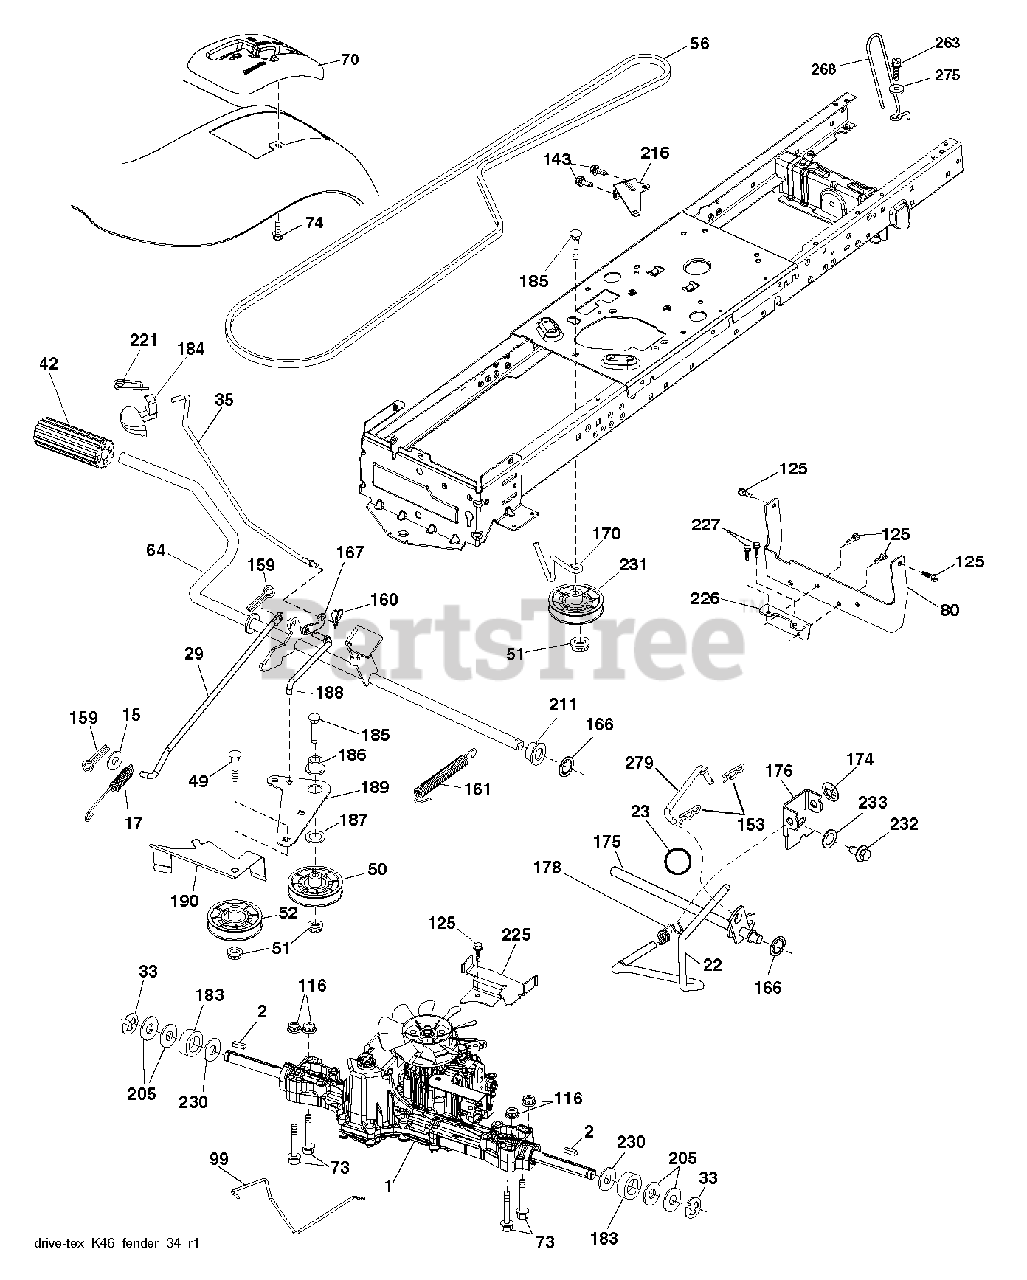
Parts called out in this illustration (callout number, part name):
2	SQUARE KEY
17	SPRING.BRAKE.K46.GREEN
22	ROD.SHIFT.FENDER.TLT.2006
23	KNOB.DUCKHEAD.1/2
29	ROD.BRAKE.K46
33	E-RING LT
35	ROD, BRAKE, PARK
42	PEDAL COVER T
49	BOLT
50	IDLER.FLAT.910.OFFSET
51	NUT LOCK FLG 3/8-16 UNC
52	IDLER.V-GROOVE.910.OFFSET
64	SHAFT.ASM.PEDAL.BRAKE.
74	SCREW.HI-LO.CONSOLE
80	STRAP.TORQUE.K46.K57R.TT
99	ROD.SPRING.BYPASS.K46.LT.Z
116	NUT LOCK HEX FLANGE 5/16-18
125	SCREW
153	RETAINER M
159	COTTER PIN
160	RETAINER CLIP
161	SPRING, RETURN LT
166	NUT.PUSH.625
167	LATCH.BRAKE.SPRING
170	KEEPER.CENTER SPAN.1.688
174	NUT.PUSH.500.2006
175	SHAFT.ASM.SHFT.T2.TLT
176	ARM.CLEVIS.ROD.SHIFT
178	SPRING.SHIFT.GT2006
183	SPACER AXLE
184	HANDLE.PARKING.BRK.PRED.LT.RED
186	SPACER.RETAINER
187	WASHER 12/32X2X10GA
188	LINK.CLUTCH.GROUND.DRIVE
189	BELLCRANK.GROUND.DRIVE.TEX.
190	KEEPER.BELLCRANK.DRIVE
211	BUSHING.SHAFT.BRAKE.HAND
216	BRACKET.PULLEY.IDLER.W/TEX
221	RETAINER.SPRING.CLIP.H
225	KEEPER.BELT.TRANSAXLE.K46
226	BRACKET.MOUNT.TORQUE.K46.TLT
227	SCREW
230	WASHER.HARDENED
231	IDLER.V-GROOVE.1.688.OFFSET
232	BOLT FIN HEX 7/16-14 X 1
233	WASHER SERRATED
263	SCREW, 3/8-16X3/4
275	WASHER
279	LINK.SHIFT.
